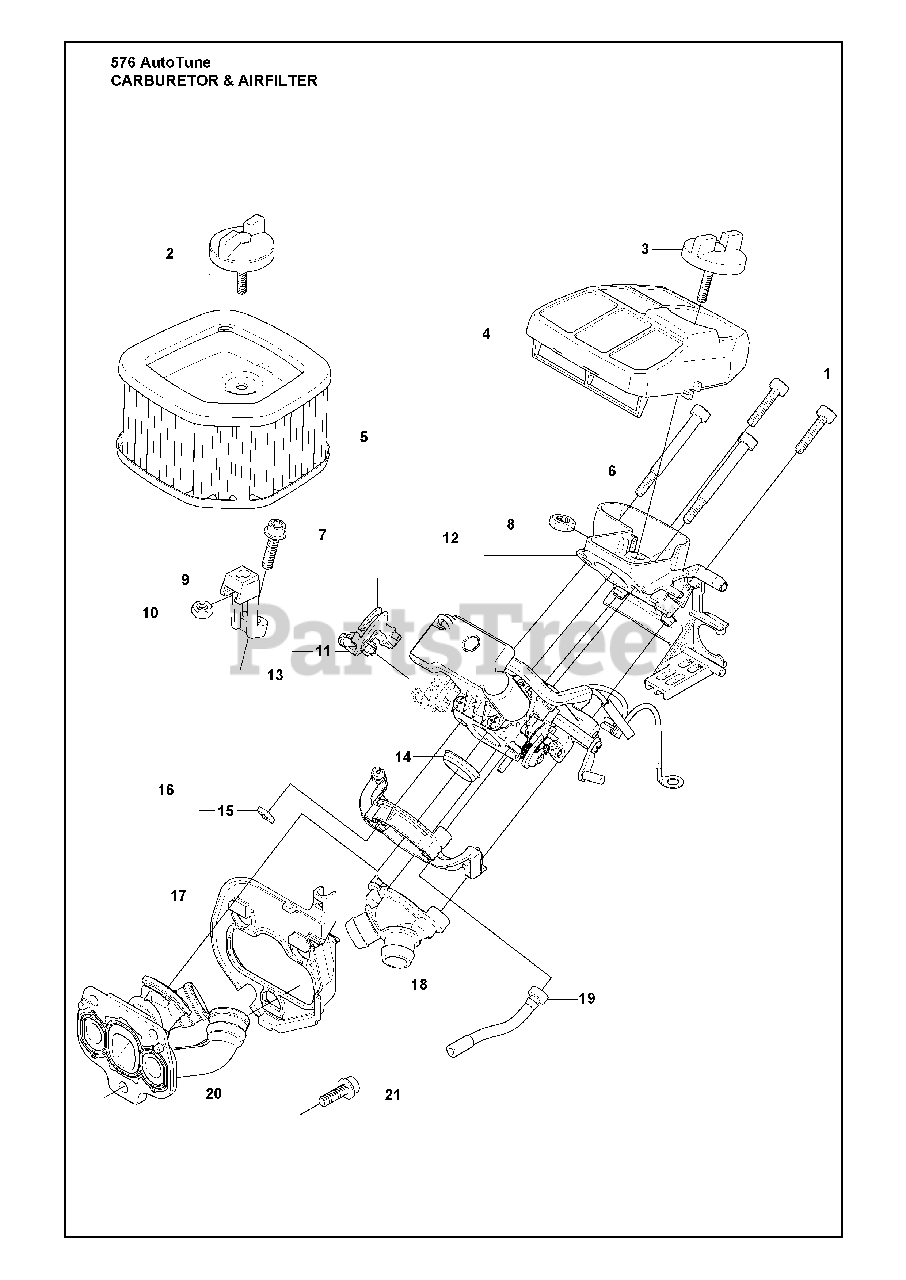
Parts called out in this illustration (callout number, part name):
4	AIR FILTER
4	RP AIR FILTER
4	%AIR FILTER
5	AIR FILTER
5	AIR FILTER 575 AUTOTUNE
6	SCREW 4X46
11	THROTTLE LEVER ASSY
12	FILTER HOLDER
13	CARBURETOR
